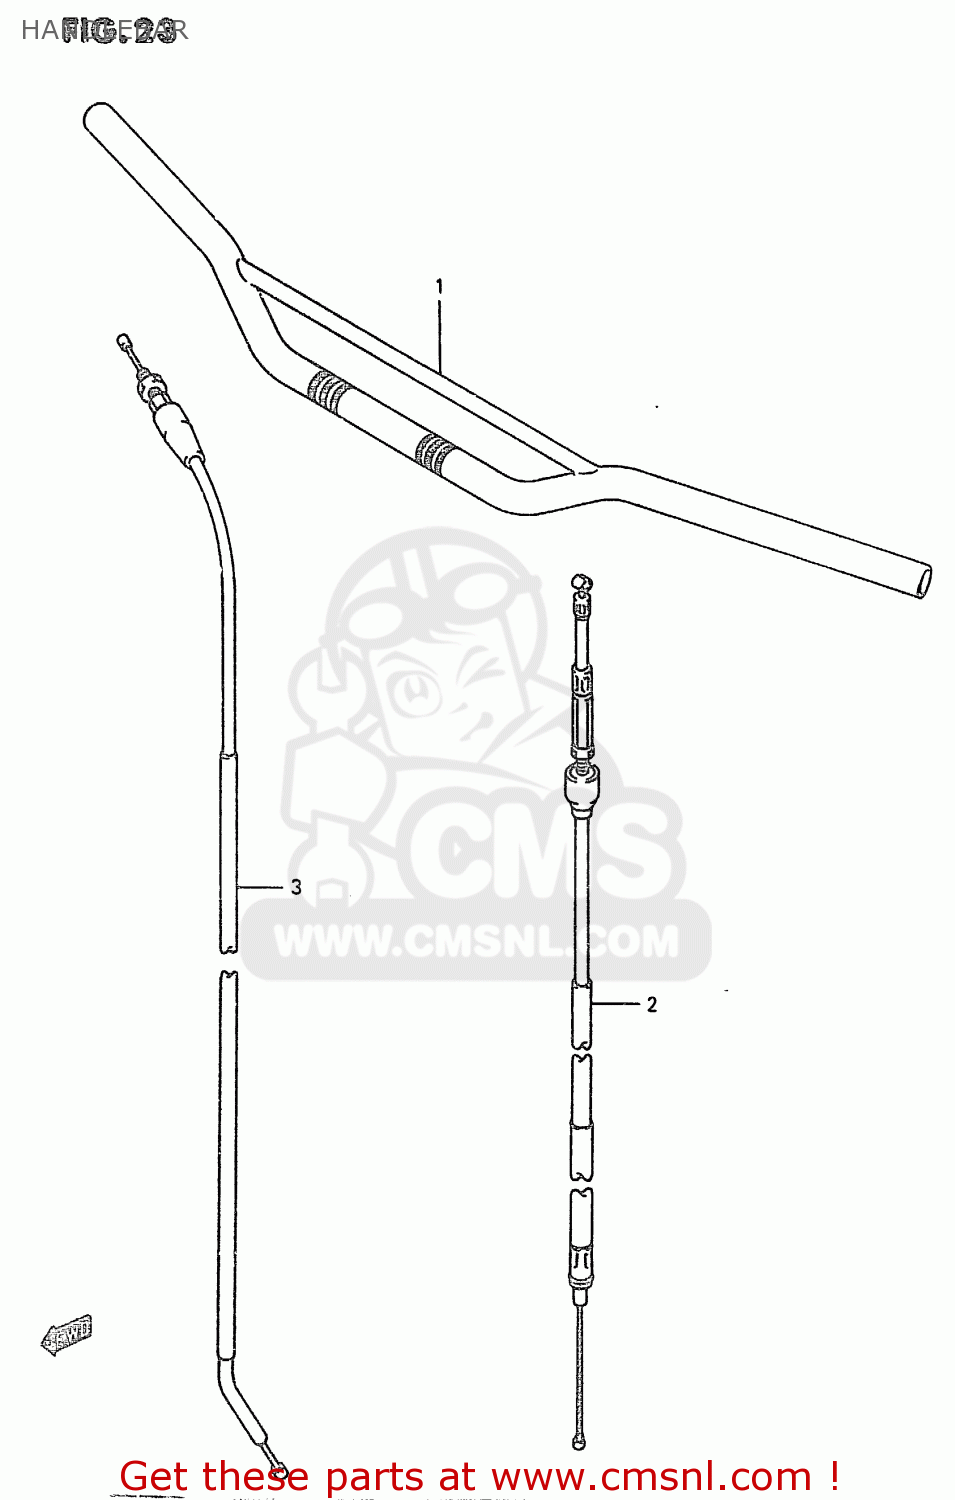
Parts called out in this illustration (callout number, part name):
1	HANDLEBAR COMP
2	CABLE ASSY,CLUTCH
3	CABLE ASSY,THROTTLE
